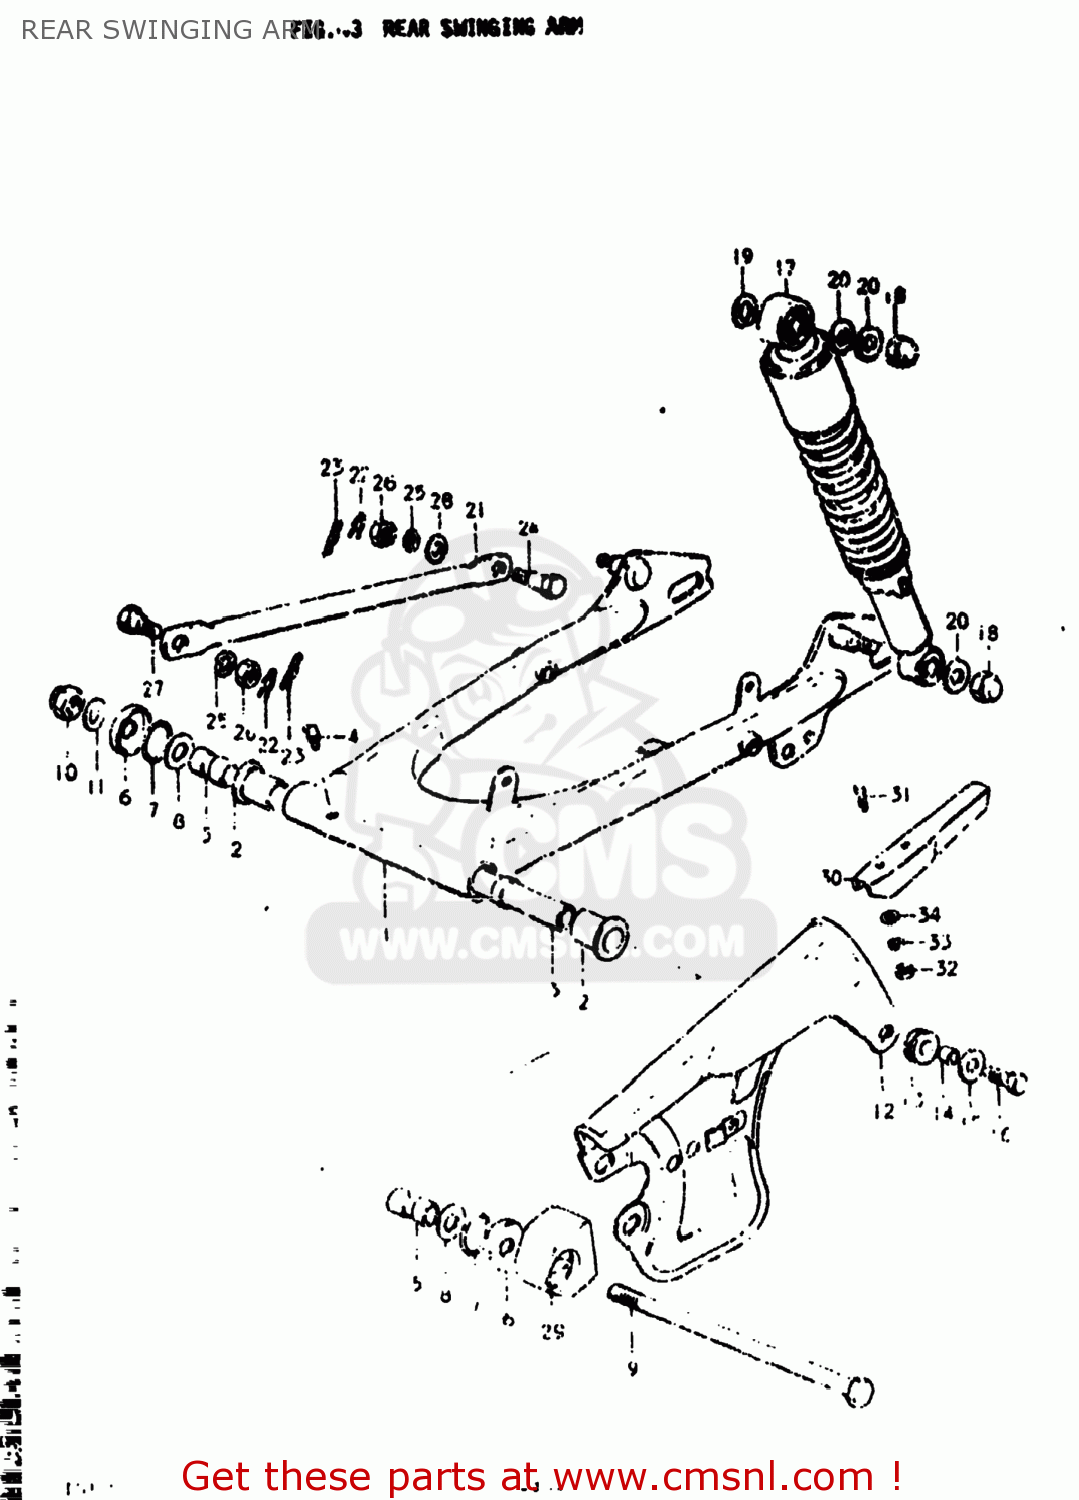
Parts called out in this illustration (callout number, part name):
1	SWING ARM ASSEMBLY,REAR
2	BUSH
3	SPACER,SWING ARM,CENTER
4	NIPPLE,GREASE
5	SPACER,RR SWGARM PIVOT
6	COVER,SWGARM BUSH DUST SEAL
7	O RING(D:2,ID:24.5)
8	WASHER(12.5X24X2.3)
9	SHAFT,PIVOT
10	NUT
11	WASHER
12	CASE,CHAIN
13	CUSHION
14	SPACER (7X9X7)
15	WASHER (6.5X20X1.2)
16	BOLT
17	ABSORBER ASSEMBLY,REAR SHOCK
18	NUT
19	WASHER
20	WASHER
21	TORQUE LINK,REAR
22	RETAINER,SNAP
23	CLIP
24	BOLT(8X26.5)
25	LOCK WASHER
26	NUT
27	BOLT(8X22)
28	WASHER 5MM
29	BUFFER,CHAIN TOUCH DEFENSE
31	BOLT
32	NUT
33	LOCK WASHER
34	WASHER
